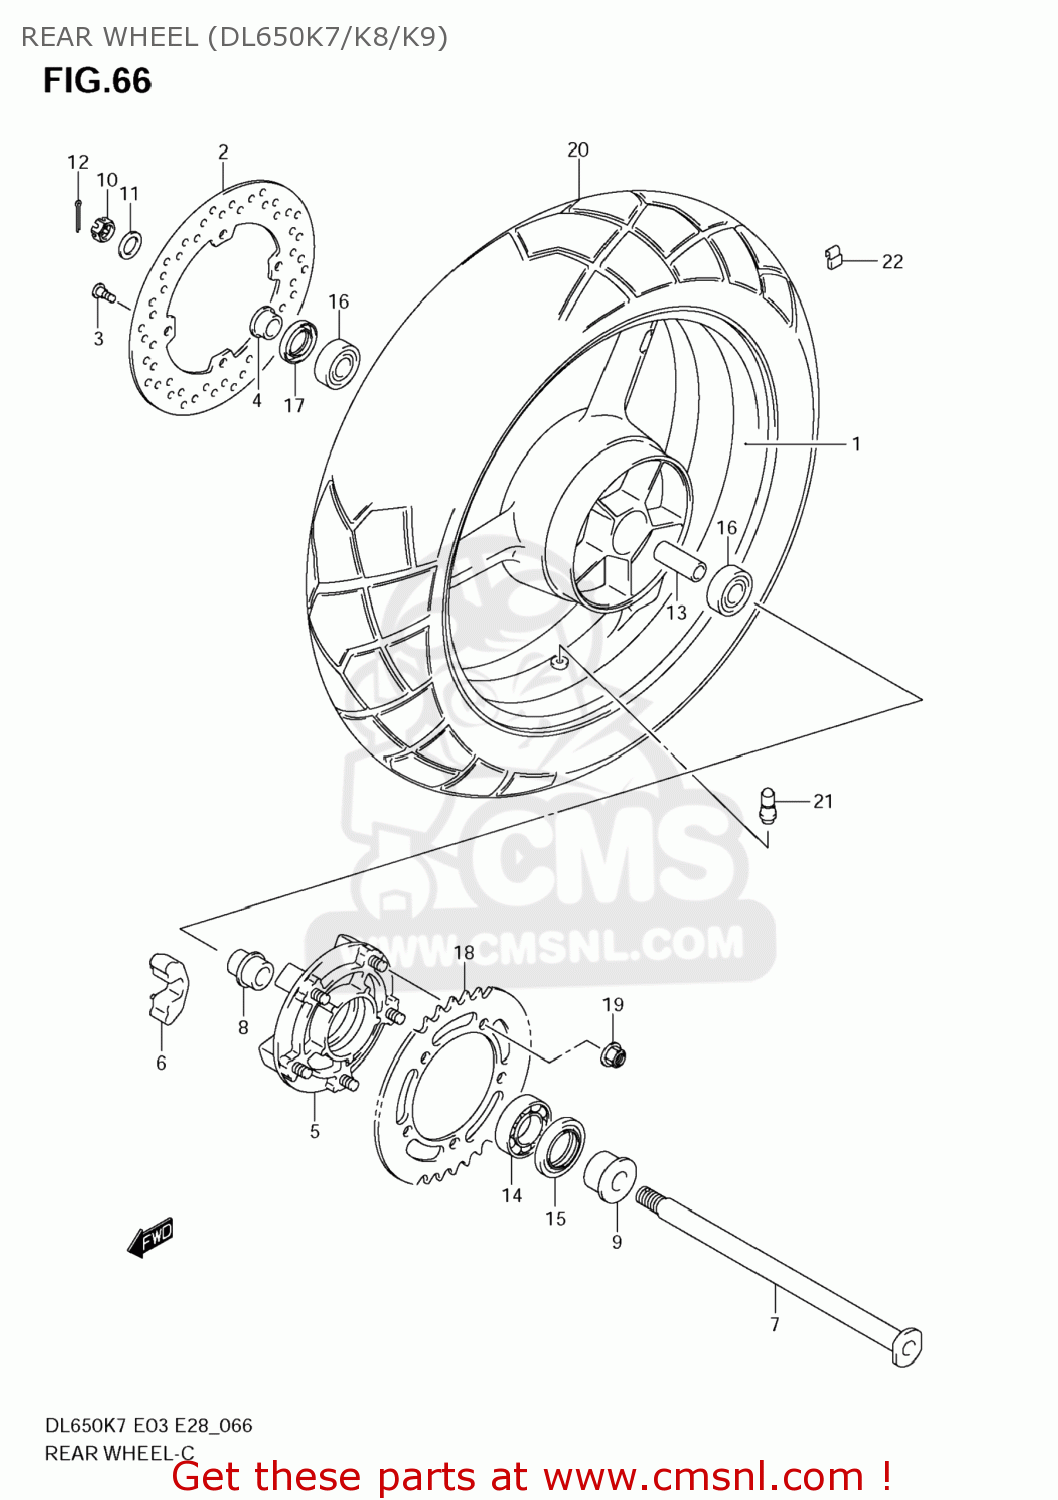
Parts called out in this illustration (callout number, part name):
1	WHEEL,RR(17M/CXMT4.00)
2	DISC,RR BRAKE
3	BOLT(8X21)
4	SPACER,RR AXLE,R
5	DRUM, REAR SPROCKET
6	ABSORBER,RR HUB SHOCK
7	AXLE,RR
8	RETAINER,RR SPROCKET DRUM
9	SPACER,RR AXLE,L
10	NUT
11	WASHER(18.5X28X2.6)
12	PIN
13	SPACER(20.8X27.2X124)
14	BEARING
15	SEAL,OIL(39X65X7)
16	BEARING
17	SEAL,OIL(28X47X7)
18	SPROCKET,RR(47T-525)
19	NUT
20	TIRE,REAR,150/
21	VALVE ASSY,WHEEL RIM(TR412)
22	WEIGHT,WHEEL BALANCE 10G
